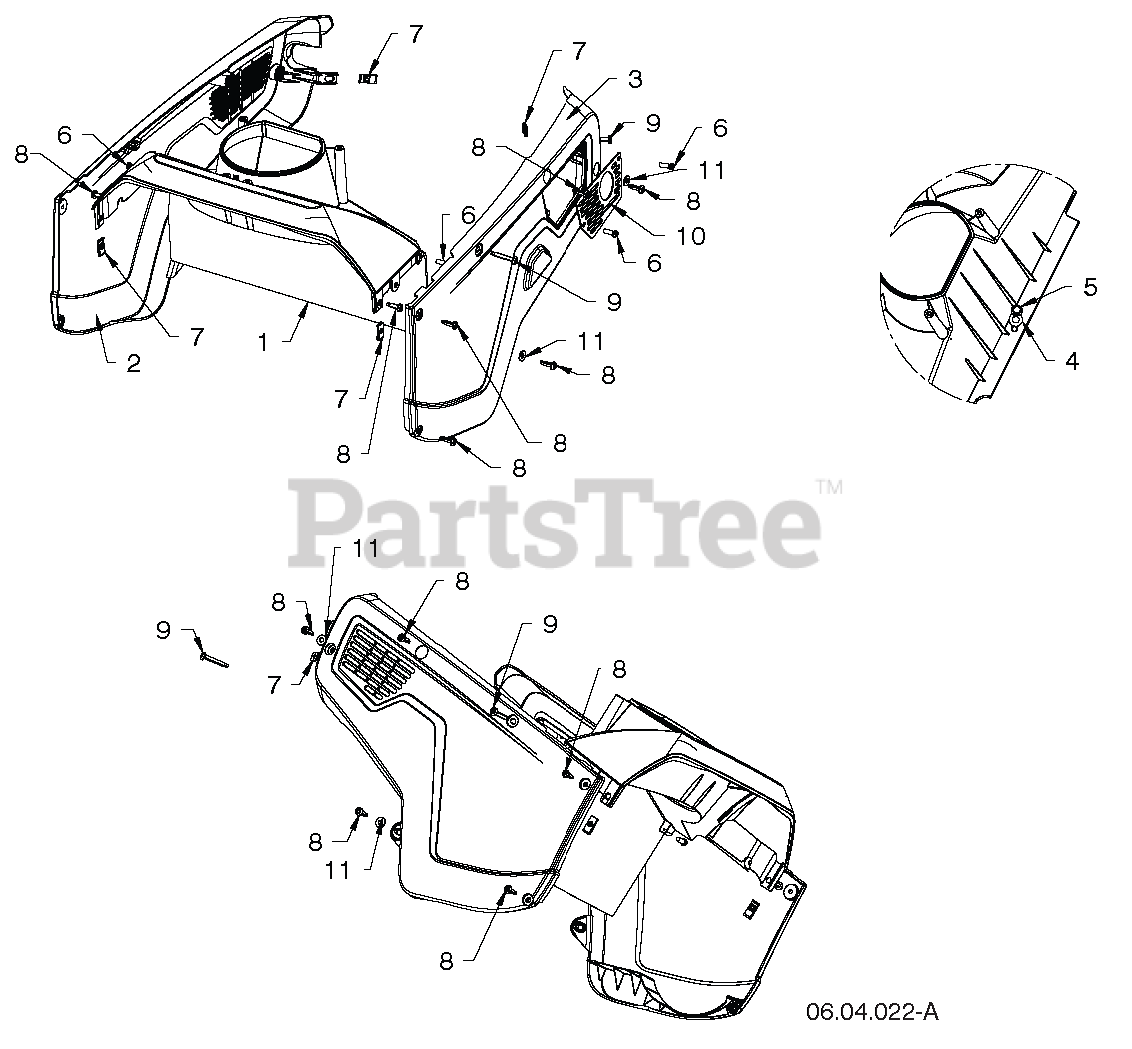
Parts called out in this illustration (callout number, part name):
1	AUGER.PLENUM.SINGLE.STAGE.GREY
2	COVER.NON-DRIVE.SIDE.HUS.ST131
3	COVER.DRIVE.SIDE.HUSQ.GY.ST131
4	WASHER
5	BOLT.HEX.HD.WASHER.5/16-18X.75
6	SCREW.HX.13X.750
8	SCREW.PAN.HD.TORX.1/4-20X.750
9	SCREW.1/4-20.PAN.HEAD.TORX.
10	PLATE.EXHAUST.SINGLE.STAGE.SNO
